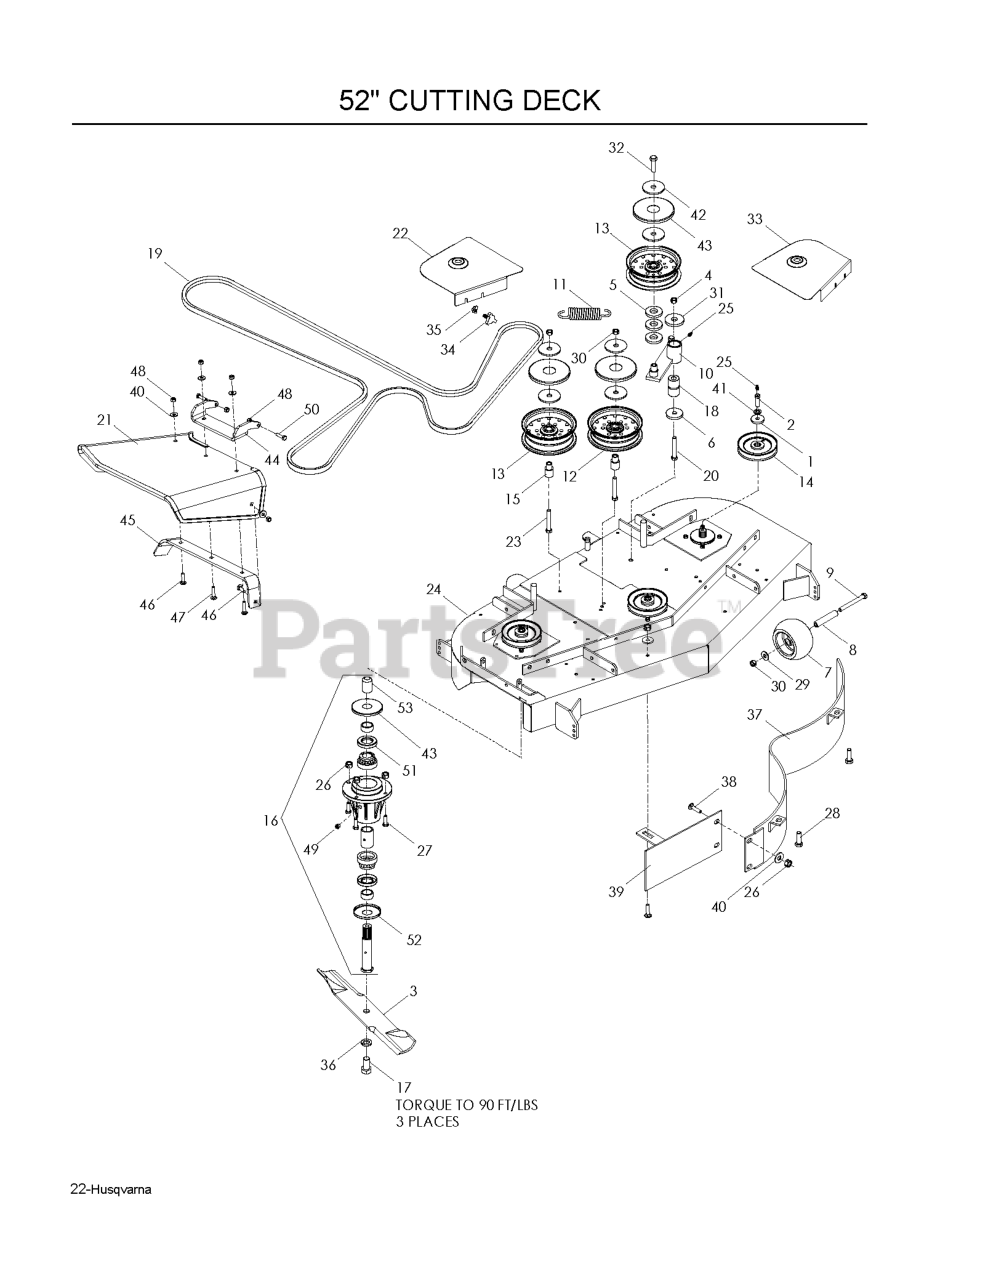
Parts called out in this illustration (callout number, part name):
1	SPINDLE WASHER
2	HCS 7/16-20 GD 8 SPEC
3	BLADE OEM 18"
4	NUT 1/2-13 HEX NYLOC ZD
6	WASHER, SUPPORT
7	ANTI-SCALP ROLLER
9	HCS 3/8C X 3 1/2
11	DECK SPRING
12	IDLER PULLEY
13	IDLER PULLEY (TALL)
14	PULLEY, 52
15	IDLER BUSHING
16	HOUSING ASM, 52/61
17	HCS 5/8F X 1 1/4
18	PIVOT BUSHING
19	BELT, DECK 52"
20	HCS 1/2C X 3 1/4
21	CHUTE, RUBBER DISCHARGE 52/61"
22	RT 52 SHIELD, ORANGE
23	HCS 3/8C X 3
24	DECK W/DECALS 52" HUS
25	ZERK
26	NUT 5/16C CENTERLOCK
27	HCS 5/16C X 1
28	HCS 5/16C X 3/4
29	WASHER 3/8 FLAT
30	NUT 3/8C CENTERBLOCK
31	WASHER 1/2 FLAT
32	HCS 3/8C X 1 1/4 GR5
33	LT 52 SHIELD ORANGE
34	KNOB W/STUD
35	U-CLIP 5/16-18 NUT RETAINER
36	LOCKWASHER 5/8
37	MAIN BAFFLE 52"
38	CARRIAGE BOLT 5/16C X 5/8"
39	CENTER BAFFLE - 52"
40	WASHER 5/16 FLAT
41	WASHER 7/16 LOCK
42	WASHER, 3/8 SPEC
43	TOP DUST CAP
44	PIVOT BRACKET - CHUTE
45	BRKT, REINF - CHUTE 52/61"
46	BOLT, CARRIAGE 5/16X1-1/4
47	RHSNB 5/16-18 X 1-1/2 GR 5 ZD
48	NUT 5/16 NYLOC
49	PLUG-VENTED
50	HCS 5/16C X 1 1/4
51	SHAFT SEAL
52	BOTTOM DUST CAP
